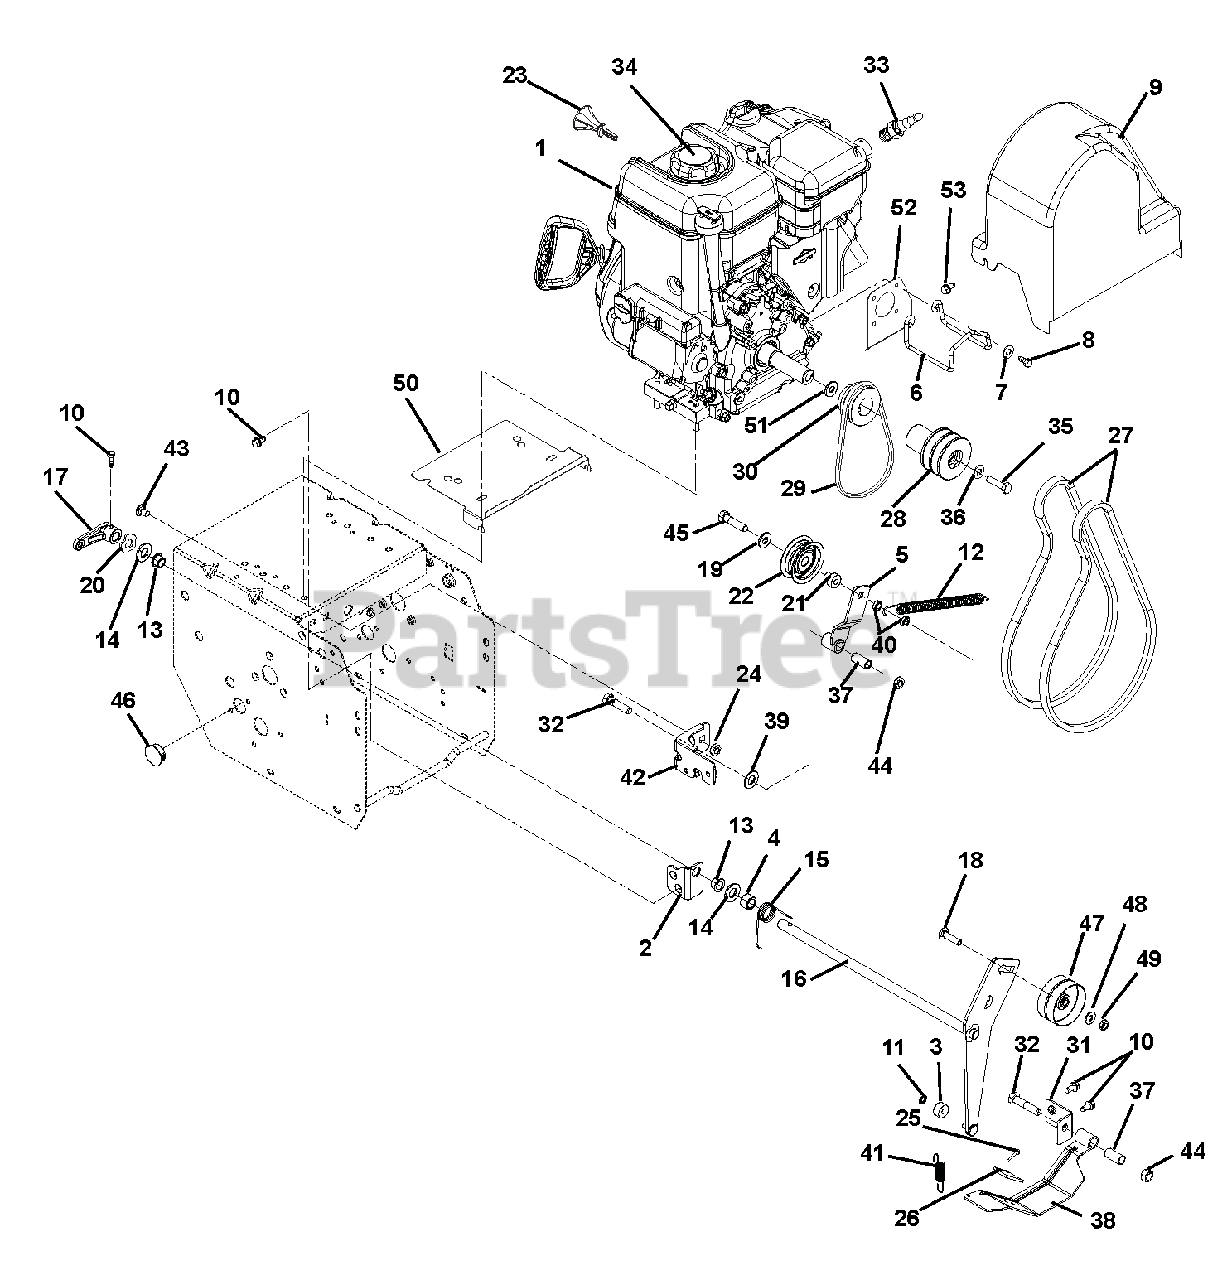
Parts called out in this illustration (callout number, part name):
1	ENGINE, BRIGGS SNOW 1150, 120V
1	ENGINE, BRIGGS SNOW 1450, 120V
1	ENGINE, BRIGGS SNOW 1650, 120V
1	ENGINE, BRIGGS SNOW 1150, 240V
1	ENGINE, BRIGGS SNOW 1450, 240V
1	ENGINE, BRIGGS SNOW 1650, 240V
2	BRACKET, MOUNT - IDLER ARM
3	BSHG,SLV .265 X .625 X .375
4	BSHG-SLV .510X.751X.475
5	WELDMENT, TRACTION IDLER ARM
6	FINGER, BELT
7	WSHR-LK .312X.097 HVY YWZC
8	BLT-HEX .31-24X.75 YWZC GR5
9	BELT COVER
10	SCR-TAP .25-20X.50 HWH TR YWZ
11	RG-RTNG-EXT .250X.010
12	SG-TENS .062X.56X8.0 WLD 11
13	BUSHING, POLYLINER-.50 SPLIT
14	WSHR-FL-STL.531X1.00X.063 YWZC
15	SG-TORS .075 X .955
16	WELDMENT, ATTACHMENT IDLER ARM
17	ARM, CLUTCH - ATTACHMENT
18	@BLT-RHDSSQNK .38-16X1.75 G5YZ
19	@WSHR-FL-STL.38X.875X.083 YWZC
20	WSHR-WAVE .50X.75X.015 .13FRHT
21	SPCR, BRG .315X.50X.688X.281
22	IDLER
23	KEY, PUSH/PULL BRIGGS
23	KEY, IGNITION ROTARY B&S
24	@NUT-LK-TOP-FLG .31-18 YWZC
25	RVT-POP .187 YZ
26	PAD, BRAKE
27	V-BELT, HA-RAW EDGE (SET)
28	SHEAVE, ATTACHMENT 2-GRV
29	V-BELT, 3L-WRAPPED
30	SHEAVE, DRIVE
31	BRACKET, BRAKE MOUNT
32	@BLT-HEX .38-16X1.75 GR5 YWZC
33	PLUG, SPARK
34	CAP, FUEL - BRIGGS & STRATTON
35	BLT-HEX .38-24X2.25 YWZC GR5
36	@WSHR-LK .38X.094 REG YWZC
37	BSHG-SLV .385X.500X1.045
38	BRAKE ARM W/PAD
39	@WSHR-FL-STL.406X.812X.065 YWZ
40	@NUT-LK-CTR-JAM .31-18 YWZC
41	SPRING-EXT .047 X .438 X 1.85
42	WELDMENT, FRAME BRACKET
43	@BLT-RHDSSQNK .31-18X.62 G5YZ
44	@NUT-LK-TOP-FLG .38-16 YWZC
45	@BLT-HEX .31-18X1.50 GR5 YWZC
46	PLUG, HOLE - .875" NYLON
47	IDLER, FLAT-2.75 OD X .375 ID
48	@WSHR-FL-STL.38X.875X.083 YWZC
49	@NUT-LK-CTR-JAM .375-16 YWZC
50	BAFFLE,ENGINE,SMALL BLOCK
50	BAFFLE, BRIGGS MDL 20/21 WATER
51	WSHR-FL-STL- 1.062X2.0X.134 YZ
52	BAFFLE, PRIMARY WATER
53	SCR-TAP .25-20X.50 LGHWH TR YZ
